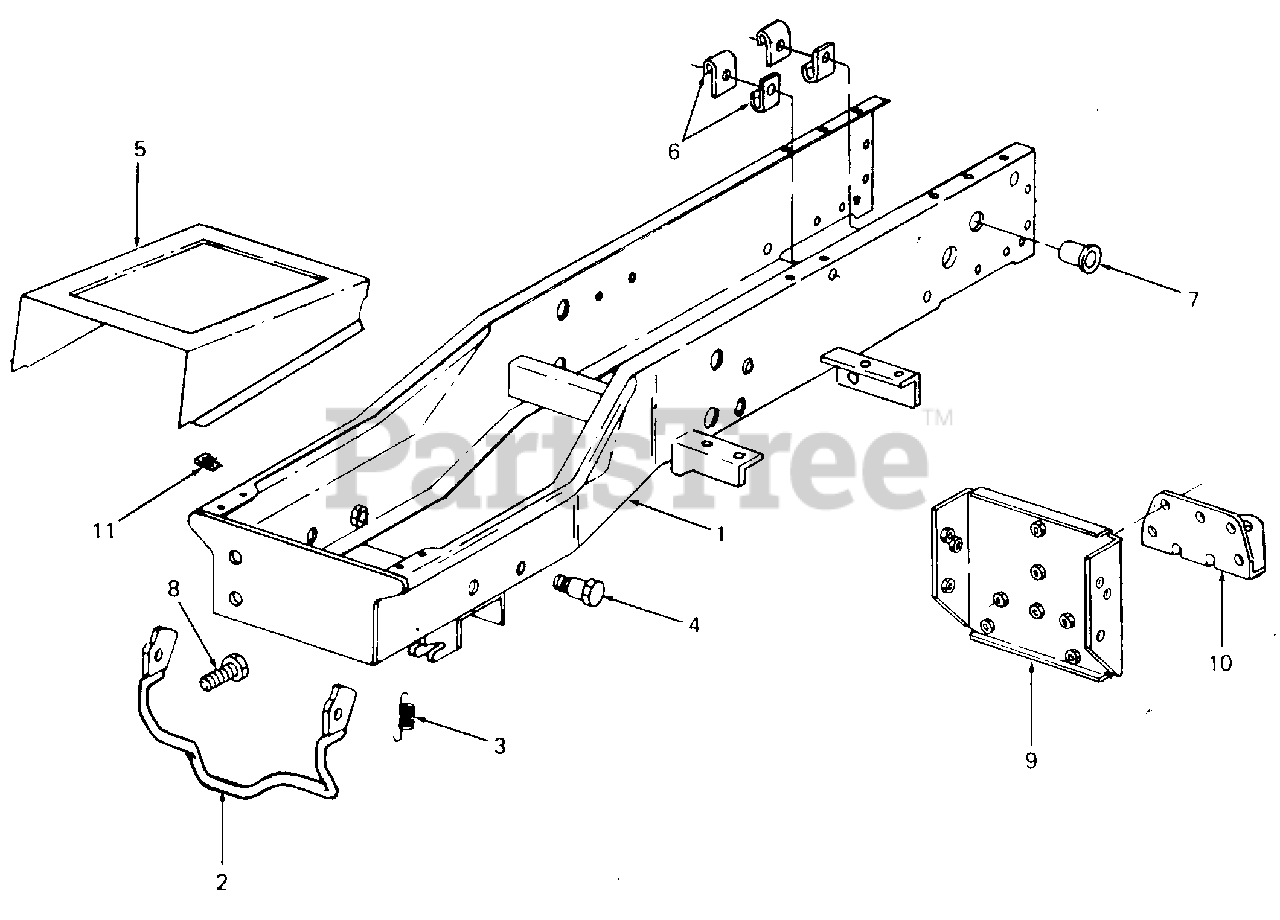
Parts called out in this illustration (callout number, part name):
1	Frame Assy
3	Spring, Latch
4	Bolt, Shoulder
5	Cover, Frame w/Graphic
6	Clip, Cable
7	Bushing, Snap
8	Screw, Adjustment, 1/2-20 X 1.0 Lg GR5
9	Plate Assy, Hitch
11	Nut, Speed
